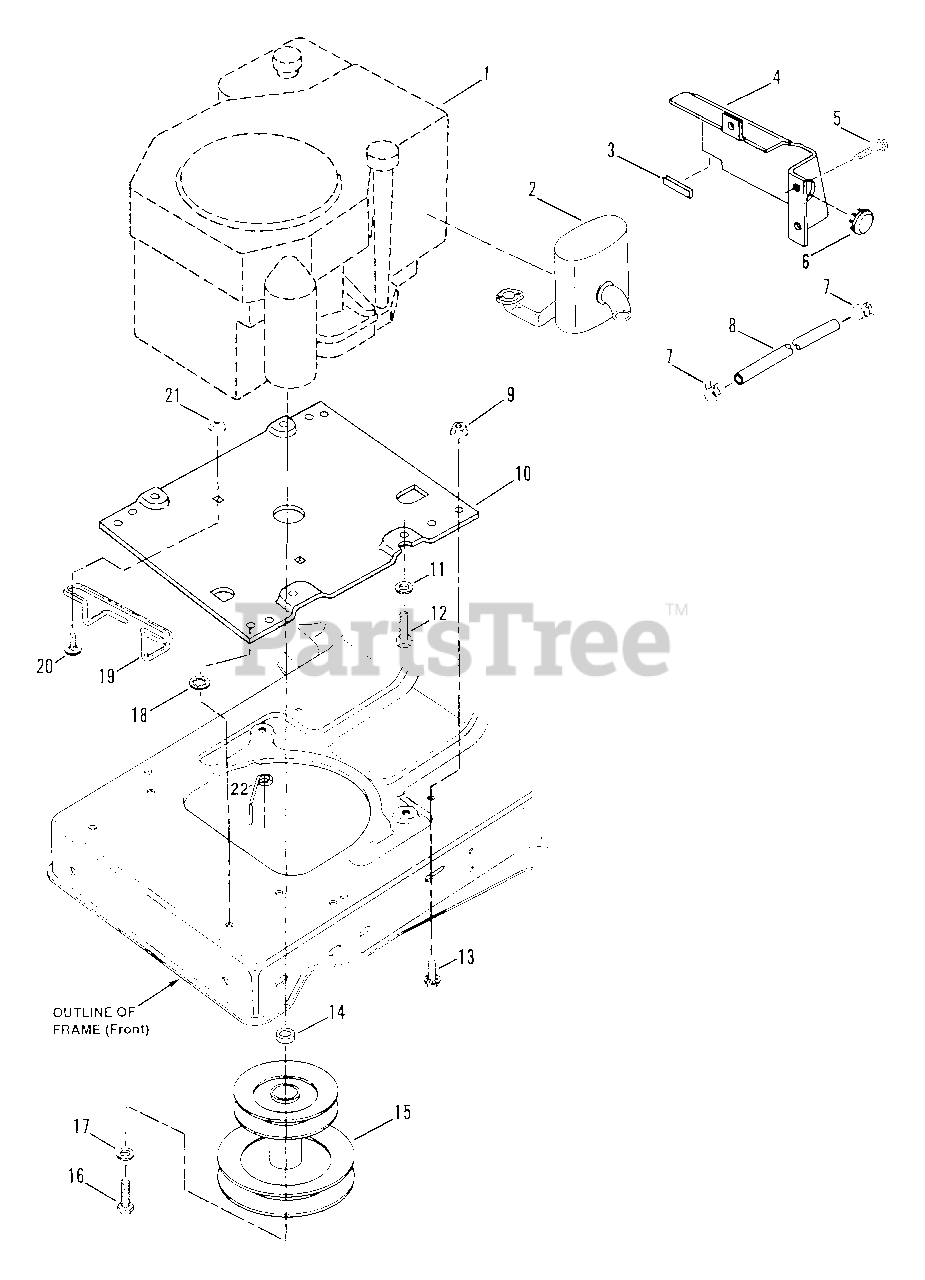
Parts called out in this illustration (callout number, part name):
2	MUFFLER
3	TRIM, Heat Shield
4	HEAT SHIELD, Valve Cover
5	SCREW, 1/4-20 x 1" Hex Head Cap, Grade 5
6	PLUG, Heat Shield
7	CLAMP, Fuel Line
8	LINE, Fuel
9	NUT, 5/16-18 Hex Flange Lock
10	SUB-PLATE, Kohler Engines
11	WASHER, 5/16 Split Lock
12	BOLT, M8 -1.25 x 25MM, Grade 5
13	BOLT, 5/16-18 x 1" Hex Flange Lock
15	PULLEY ASSEMBLY
16	SCREW, M10-1.50 x 40MM Hex Head Cap
17	WASHER, M10 Split Lock
18	WASHER, 5/16 Internal Tooth Lock
19	GUIDE, Belt
20	BOLT, 1/4-20 x 5/8" Short Neck Carriage, Grade 5
21	NUT, 1/4-20 Hex Flange Lock
22	GUIDE, Belt
